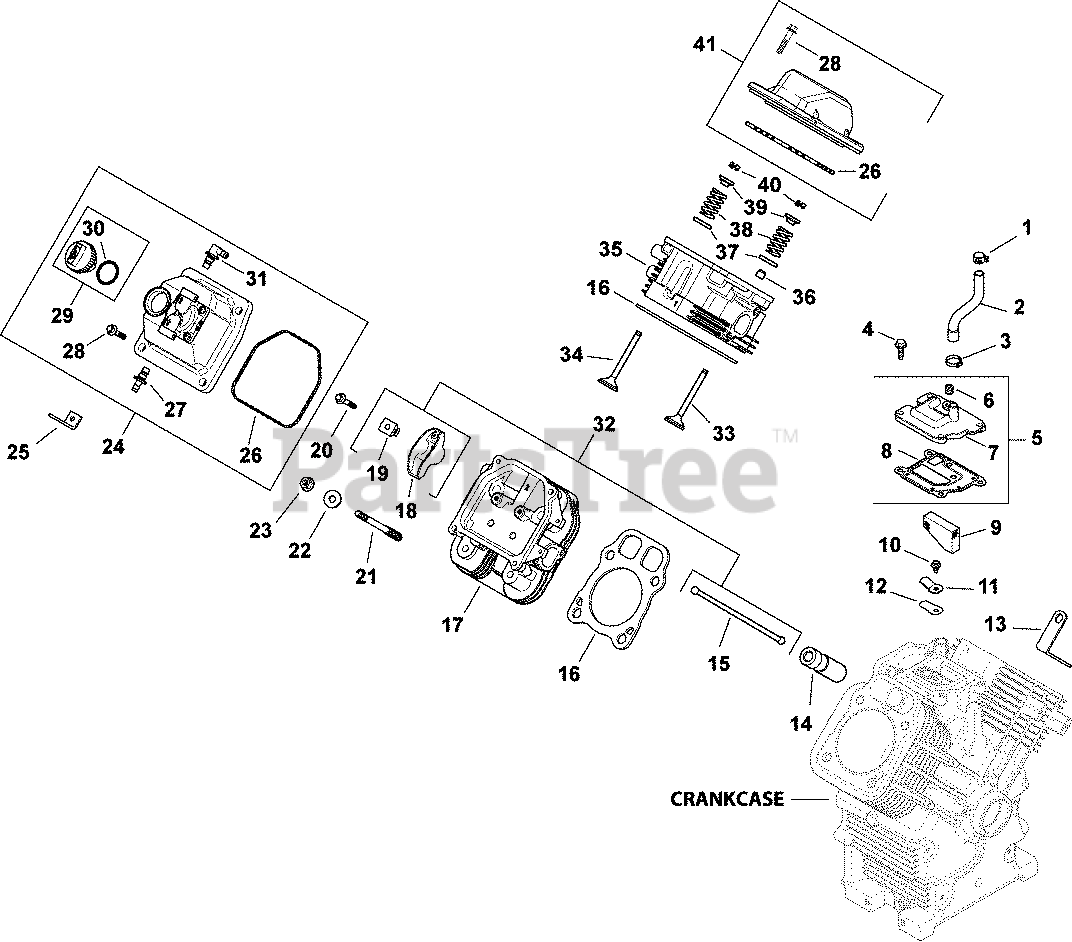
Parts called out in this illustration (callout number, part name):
1	CLAMP, BAND SPRING HOSE-(#2523737S)
2	HOSE, BREATHER
3	CLAMP, HOSE (KM)-USE 25 237 31-S
4	SCREW,FLG THD FRM M6X1.0X20-(#25086396S)
5	KIT, BREATHER ASSEMBLY
6	PLUG, CTSK PIPE 1/8"
7	COVER, BREATHER -USE 24 033 01-S
8	GASKET, BREATHER-USE 24 041 67-S
9	FILTER, BREATHER
10	SCREW, FLG THD FRM M5X.8X10
11	RETAINER, REED
12	REED, BREATHER
13	STRAP, LIFTING-USE 25 445 03-S
14	LIFTER, HYDRAULIC VALVE-USE 25 351 10-S
15	ROD, PUSH
16	CYL HEAD GASKET KIT-USE 24 841 04-S
17	HEAD, SERVICE ASSY CYL #2-USE 24 318 114
18	ARM, ROCKER
19	PIVOT, ROCKER ARM
20	SCREW, FLG M6X1.0X34
21	STUD, M8X1.25
22	WASHER, FLAT 8.6 MM
23	NUT, FLG M8X1.25
24	KIT, VALVE COVER-FUEL PUMP
26	O-RING (YELLOW), VALVE COVER
27	KIT, STRAIGHT FITTING
28	SCREW, FLG M6X1.0X30
29	CAP ASSY, OIL FILL (YELLOW)
30	O-RING-USE 24 153 32-S
31	KIT, 90 DEG. FITTING
32	KIT, VALVE TRAIN
33	VALVE, INTAKE (STD)
34	VALVE, EXHAUST (STD) - USE 32 016 01-S
35	HEAD, SERVICE ASSY CYL #1-USE 24 318 106
36	SEAL, VALVE STEM - (#2503214S)
37	RETAINER, SPRING
38	SPRING, VALVE
39	RETAINER, VALVE SPRING - USE 25 173 28-S
40	KIT, RETAINER
41	KIT, VALVE COVER-PLAIN (PLASTIC)
2401602-S	VALVE, EXHAUST (.25)
2401702-S	VALVE, INTAKE (.25)
